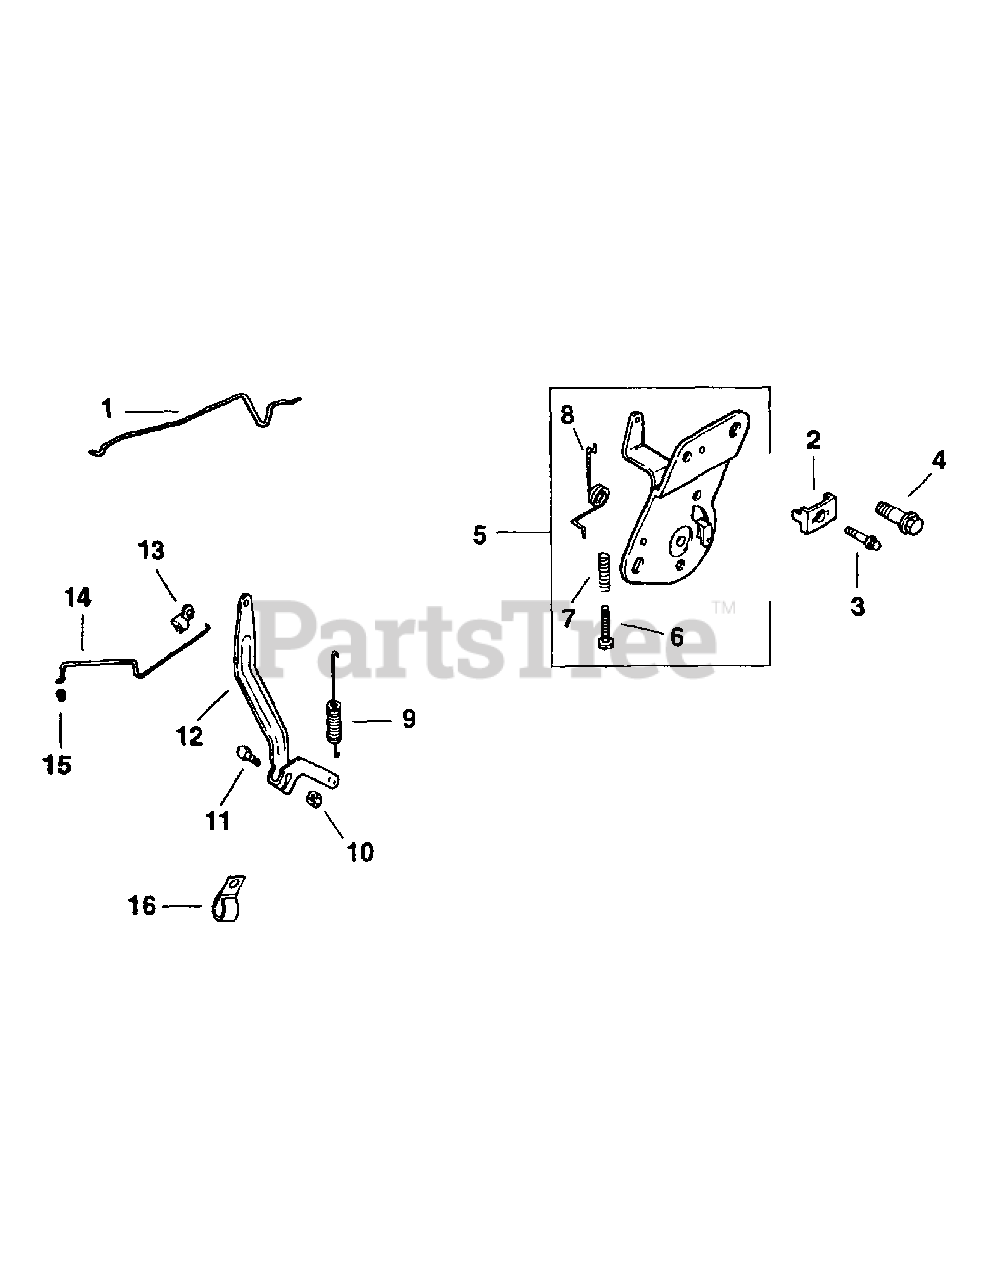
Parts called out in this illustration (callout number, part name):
1	Linkage, Choke
2	Clamp, Cable
3	Screw, Hex Flange
4	Screw, Hex Flange
5	Speed Control Assembly
6	Screw, Pan hd.
7	Spring, Choke
8	Spring, Choke Return
9	Spring, Governor
10	Nut, Hex Flange
11	Screw, Hex Cap
12	Lever, Governor
13	Bushing, Linkage Black
14	Linkage, Throttle
15	Bushing, Linkage Natural
